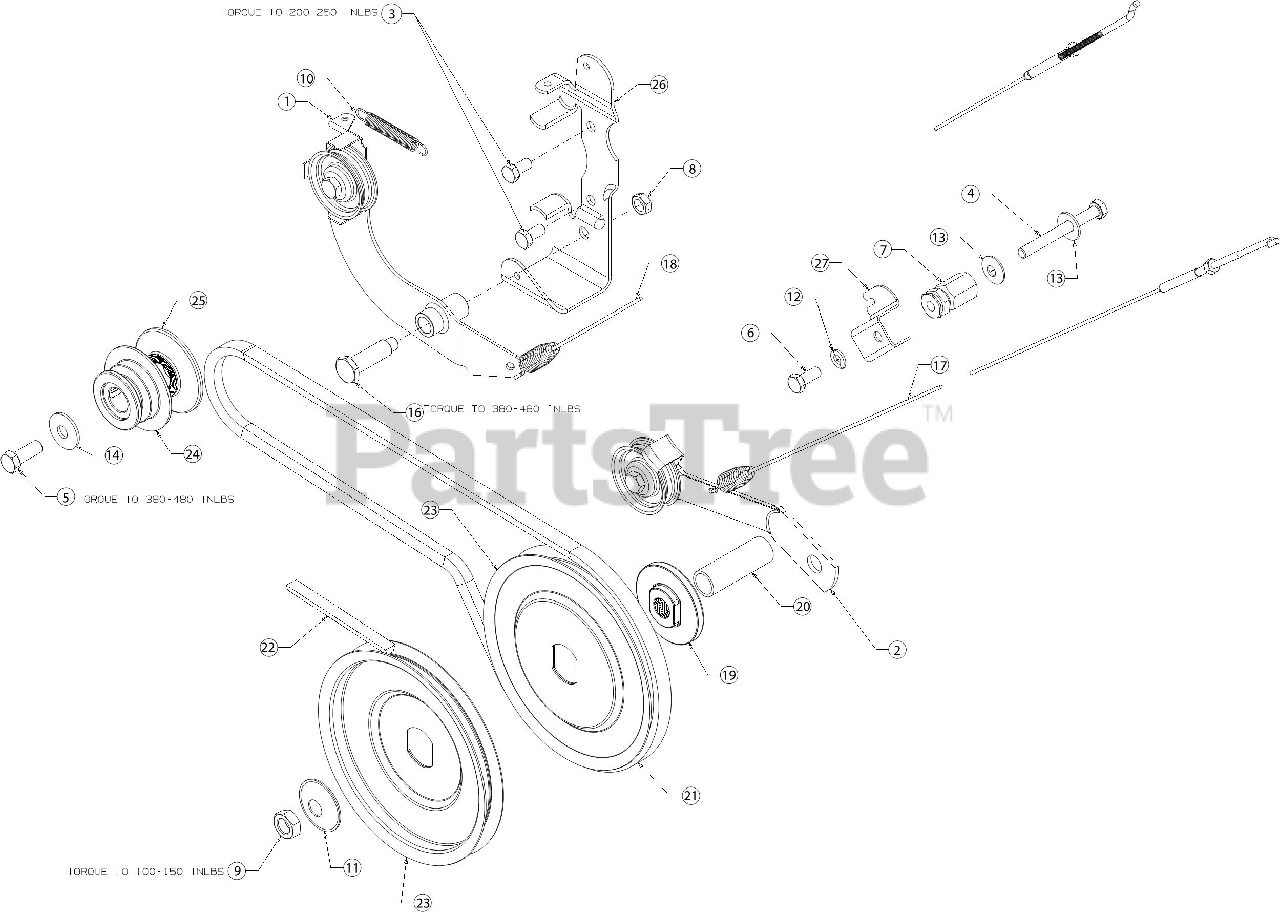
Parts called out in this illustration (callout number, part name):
1	REVERSE ARM ASSEMBLY
1	SCREW 3/8-16 X 1.25 GR5
1	JAM LOCK NUT
1	IDLER PULLEY
2	IDLER BRACKET ASSEMBLY
2	SCREW 3/8-16 X 1.25 GR5
2	JAM LOCK NUT
2	IDLER PULLEY
2	IDLER BRACKET
2	BELT KEEPER
3	HEX SCREW 5/16-24 X .62
4	HEX SCREW 5/16-18 X 3.00
5	SCREW 3/8-24 X 1.00 GR8
6	SCREW 5/16-18 X .75 GR5
7	SPECIAL HEX NUT
8	JAM LOCK NUT
10	EXTENSION SPRING
11	BELL WASHER .535 ID X1.50 OD X.052
12	LOCK WASHER 5/16
13	BELL WASHER .337 X.867 X .057
14	BELL WASHER
15	GREASE
16	SHOULDER SCREW .498
18	CONTROL CABLE
19	PULLEY MOUNTING ADAPTER
22	BELT 3L X 45.68"
24	ENGINE HALF PULLEY
25	ENGINE PULLEY INNER HALF
